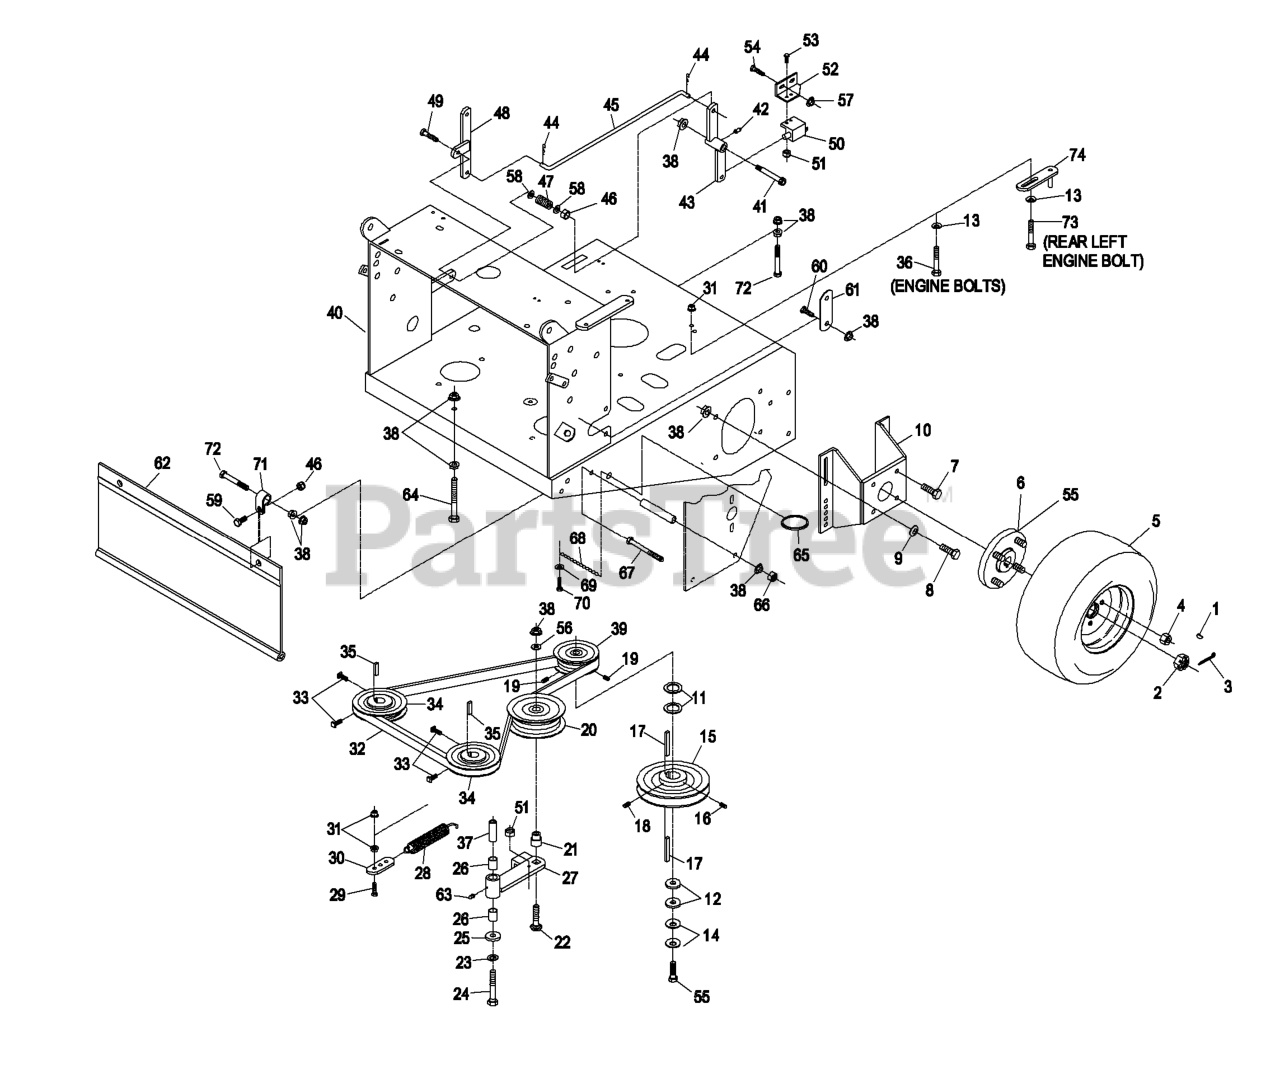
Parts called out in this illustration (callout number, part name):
1	KEY-WOODRUFF
3	PIN-COTTER
4	NUT-LUG
5	WHEEL AND TIRE ASM
7	SCREW-HHF
8	SCREW-HH
9	WASHER-BELLEVILLE
10	MOUNT-MOTOR
11	WASHER-SPACER
13	WASHER-SPRING
14	WASHER-SPRING
15	SHEAVE
16	SCREW-SET
18	SCREW-SET
19	SCREW-SET
21	BUSHING-IDLER
22	SCREW-CARR
23	WASHER-LOCK
24	BOLT-CARR
26	SLEEVE-BEARING
27	Arm, Assy Idler (W/Brgs)
28	SPRING-EXTENSION
29	SCREW-HH
30	ANCHOR-SPRING
33	SCREW-SET
34	SHEAVE ASM
36	SCREW-HH
37	BUSHING
38	NUT-HHF, WHIZ
42	FITTING-GREASE, 90 DEG
43	BELLCRANK ASM
44	PIN-COTTER
45	LINKAGE-ENGAGE, BLADE
46	NUT-LOCK, NI
47	SPRING-COMPRESSION
49	SCREW-HH
50	SWITCH-OPEN, NORMALLY
51	NUT-LOCK, NI
52	BRACKET-SWITCH, BLADE
53	SCREW-PPH
54	SCREW-HH
55	SCREW-HH
56	WASHER-FLAT
58	WASHER-PLAIN
59	SCREW-HH
60	SCREW-HH
61	ARM-LIFT, DECK
63	FITTING-GREASE
64	SCREW-HH
65	RING-SPLIT
66	NUT-LOCK, NI
67	SCREW-HH
68	CHAIN-LINK, TWIST
69	WASHER-FLAT
70	SCREW-HSH
71	CLIP-LOOM
72	SCREW-HH
73	SCREW-HH
74	GUIDE-BELT
